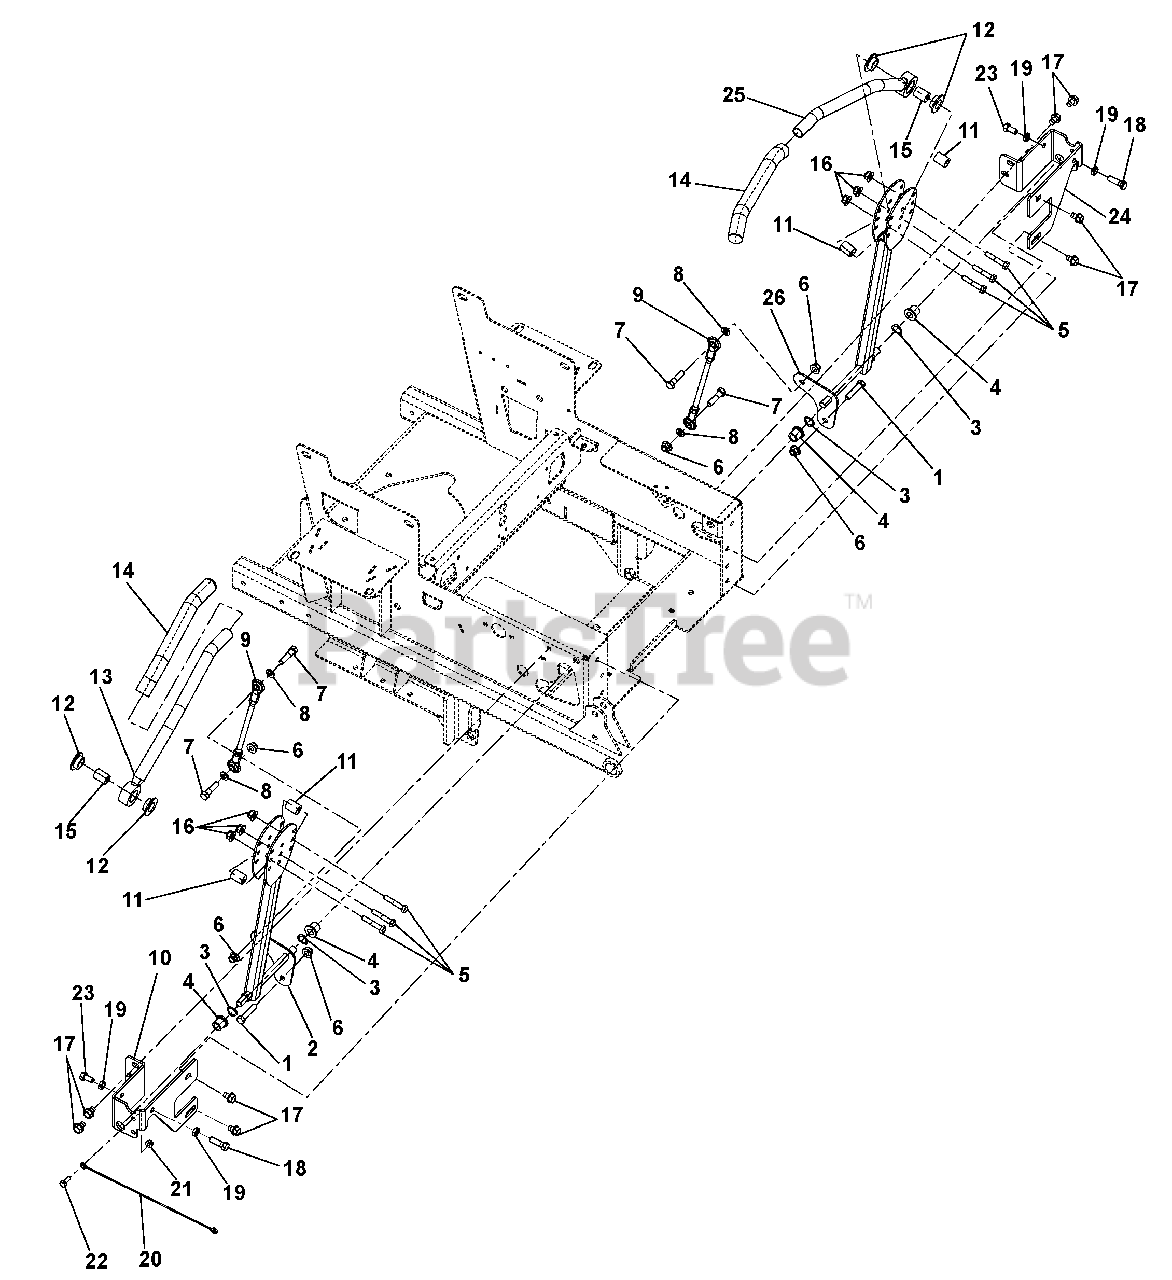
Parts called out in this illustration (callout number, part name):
1	BLT-HEX .38-16X2.0 GR5 FTD YWZ
2	WMT, RH CONTROL
3	WAVE WASHER .640X.875X.125FH
4	BSHG-FLG .515X.750X.745X1.00NY
5	BLT-HEX .31-18X1.75 GR5 YWZC
6	NUT-LK-NYL-FLG .38-16 YWZC
7	BLT-HEX .38-16X1.50 GR5 YWZC
8	WSHR-LK .38X.094 REG YWZC
9	ASM, STEERING LINKAGE
10	RH STEERING STOP BRKT - BLK
11	ECCENTRIC
12	BSHG-FLG .762X1.48X.44 NYL
13	WLDMT, RH HANDLE
14	GRIP, HANDLEBAR
15	SPACER .328 X .76 X 1.01
16	NUT-LK-NYL-FLG .31-18 YWZC
17	SCR-TAP .38-16X.50 HWH TR YWZ
18	BLT-HEX .38-16X1.25 GR5 YWZC
19	NUT-HEX-JAM .375-16 YWZC
20	CABLE, 12.0 LANYARD, NYLON
21	NUT-LK-NYL-FLG .25-20 YWZC
22	BLT-HEX .25-20X.75 GR5 YWZC
23	BLT-HEX .38-16X.75 GR5 YWZC
24	BRKT, LH STEERING STOP
25	HANDLE WLDMT LH
26	WMT, LH CONTROL
